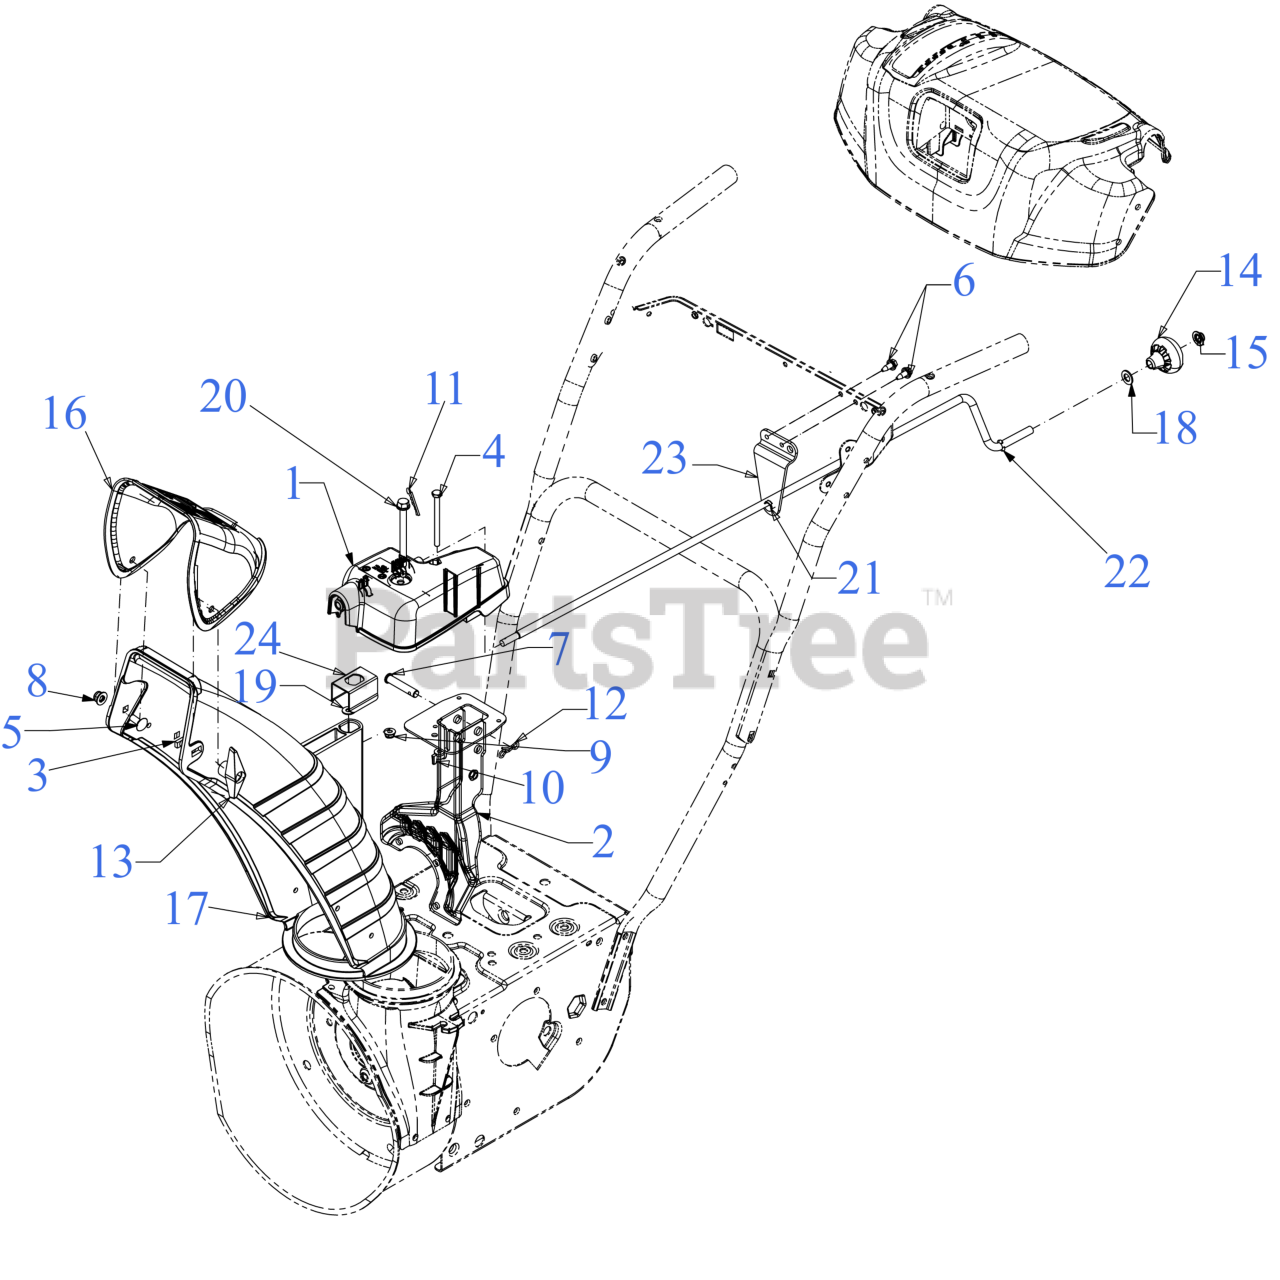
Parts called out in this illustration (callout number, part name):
1	2-WAY CHUTE ROTATE GEARBOX
2	CHUTE SUPPORT ASSEMBLY
3	CARRIAGE BOLT 5/16-18 x 1
4	SCREW 1/4-20 x 3.0 GR5
5	CARRIAGE BOLT 5/16-18 x .75
6	SCREW 1/4-20X.625
7	CLEVIS PIN 3/8 x 1.87
8	FLANGE LOCK NUT 5/16-18
9	FLANGE LOCK NUT
10	WING NUT 1/4-20
11	INTERNAL COTTER PIN
12	BOW TIE COTTER PIN 1/4-5/16
13	WING KNOB NUT
13	STAR KNOB 5/16-18
14	SHIFT KNOB
16	UPPER CHUTE (W/LBL MANUAL TILT)
17	LOWER CHUTE 5"
18	FLAT WASHER
19	FLAT WASHER
20	SHOULDER SCREW
21	BUSHING .380 ID
22	CHUTE CRANK .375 DIA x 31"
23	ROD SUPPORT BRACKET
24	CHUTE BRACKET
